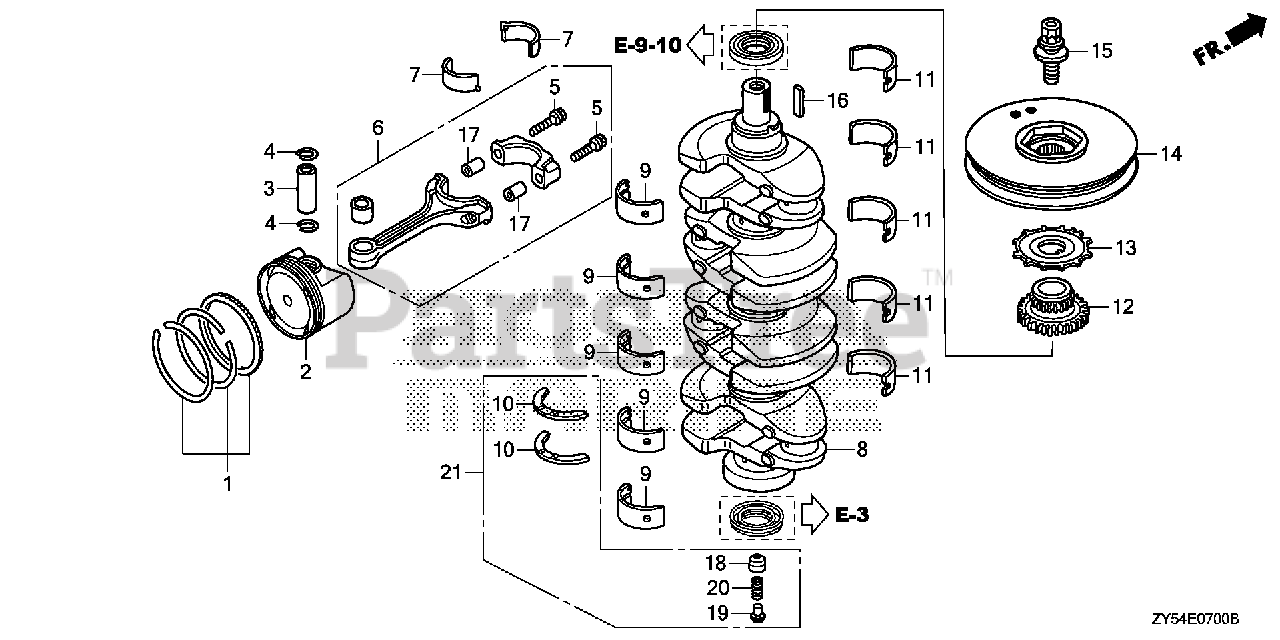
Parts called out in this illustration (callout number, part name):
1	RING SET, PISTON (STD)
3	PIN, PISTON
4	CLIP, PISTON PIN
5	BOLT, CONNECTING ROD
6	ROD, CONNECTING
7	BEARING A, CONNECTING ROD (BLUE)
7	BEARING B, CONNECTING ROD (BLACK)
7	BEARING C, CONNECTING ROD (BROWN)
7	BEARING D, CONNECTING ROD (GREEN)
7	BEARING E, CONNECTING ROD (YELLOW)
7	BEARING F, CONNECTING ROD (PINK)
8	CRANKSHAFT
9	BEARING A, MAIN (UPPER) (BLUE) (DAIDO)
9	BEARING B, MAIN (UPPER) (BLACK) (DAIDO)
9	BEARING C, MAIN (UPPER) (BROWN) (DAIDO)
9	BEARING D, MAIN (UPPER) (GREEN) (DAIDO)
9	BEARING E, MAIN (UPPER) (YELLOW) (DAIDO)
9	BEARING F, MAIN (UPPER) (PINK) (DAIDO)
10	WASHER, THRUST
11	BEARING A, MAIN (LOWER) (BLUE) (DAIDO)
11	BEARING B, MAIN (LOWER) (BLACK) (DAIDO)
11	BEARING C, MAIN (LOWER) (BROWN) (DAIDO)
11	BEARING D, MAIN (LOWER) (GREEN) (DAIDO)
11	BEARING E, MAIN (LOWER) (YELLOW) (DAIDO)
11	BEARING F, MAIN (LOWER) (PINK) (DAIDO)
12	SPROCKET, CHAIN DRIVE
13	PLATE, CRANK PULSER
14	PULLEY, CRANKSHAFT
15	BOLT-WASHER (16X49)
16	KEY (4.5X21)
17	PIN, DOWEL (10X12)
18	RETAINER, SPRING
19	SEAT, SPRING (150)
20	SPRING, SUPPORT
21	WASHER KIT, THRUST (150)
